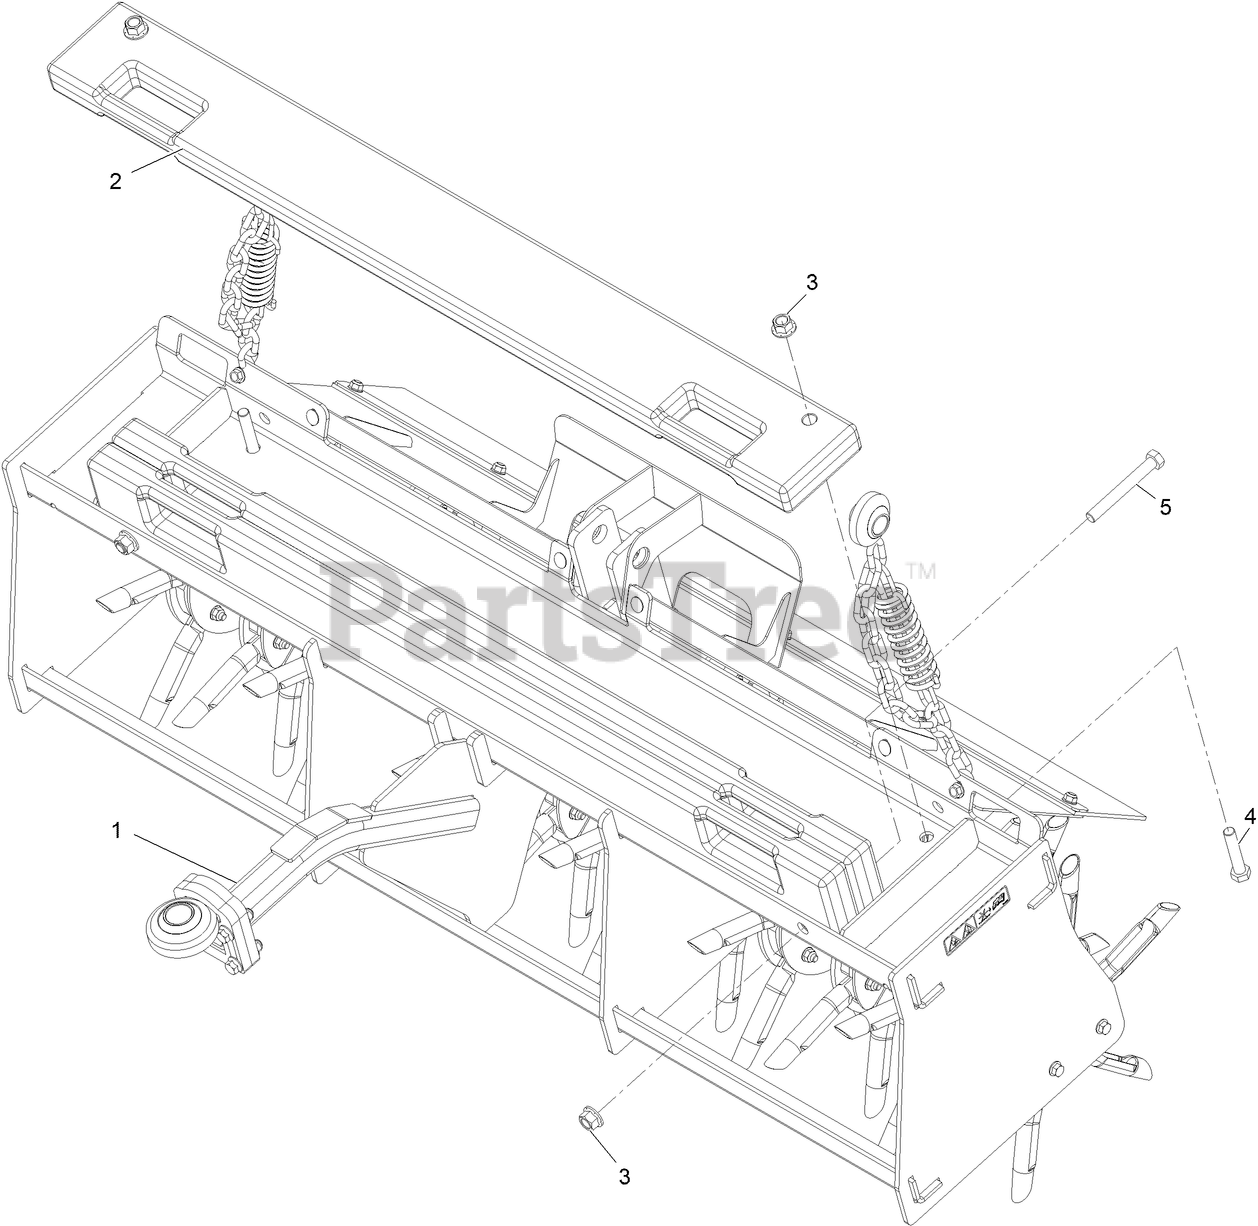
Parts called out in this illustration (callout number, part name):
1	50 Inch Aerator Head ASM
2	BAR-WEIGHT
3	Nut-Lock 1/2-13
4	SCREW-HH
5	SCREW-HH
